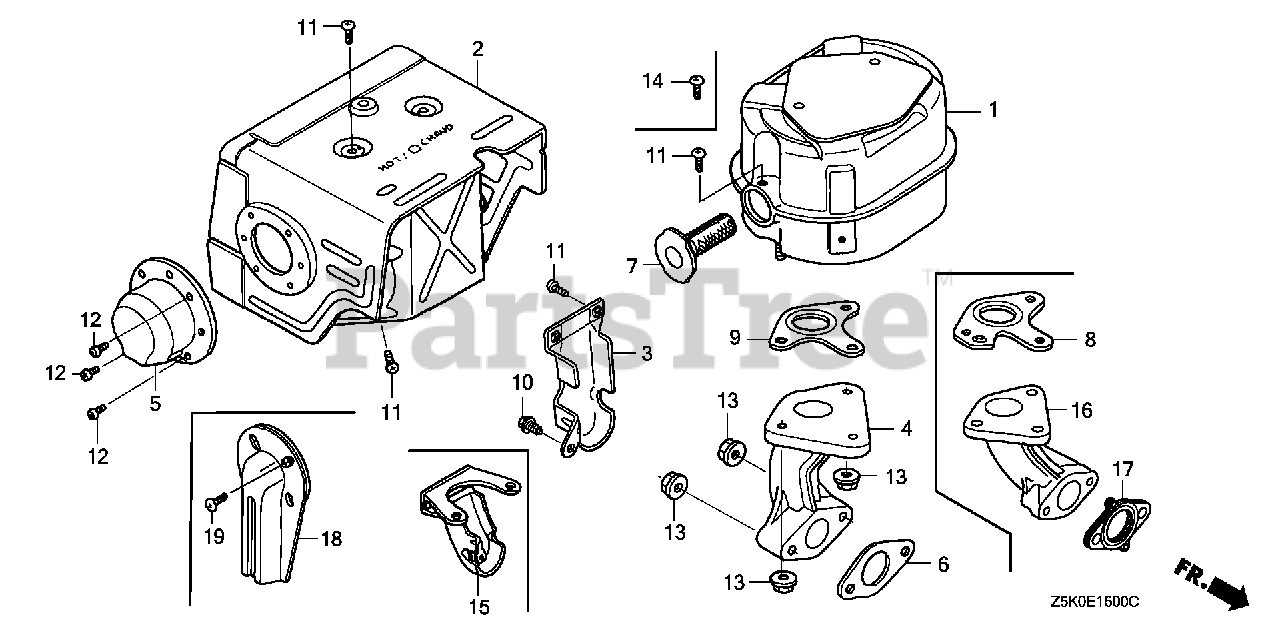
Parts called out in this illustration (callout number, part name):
1	MUFFLER
2	PROTECTOR, MUFFLER (STD)
3	PROTECTOR, EX. PIPE
5	CAP, MUFFLER
6	GASKET, EX. PIPE
7	ARRESTER, SPARK
8	GASKET, MUFFLER (ARRESTER) (NIPPON LEAKLESS)
9	GASKET, MUFFLER (THAI LEAKLESS)
10	BOLT, FLANGE (6X12) (CT200)
11	SCREW, TAPPING (5X8)
12	SCREW, TAPPING (4X6)
13	NUT, FLANGE (8MM)
14	SCREW, TAPPING (4X6)
